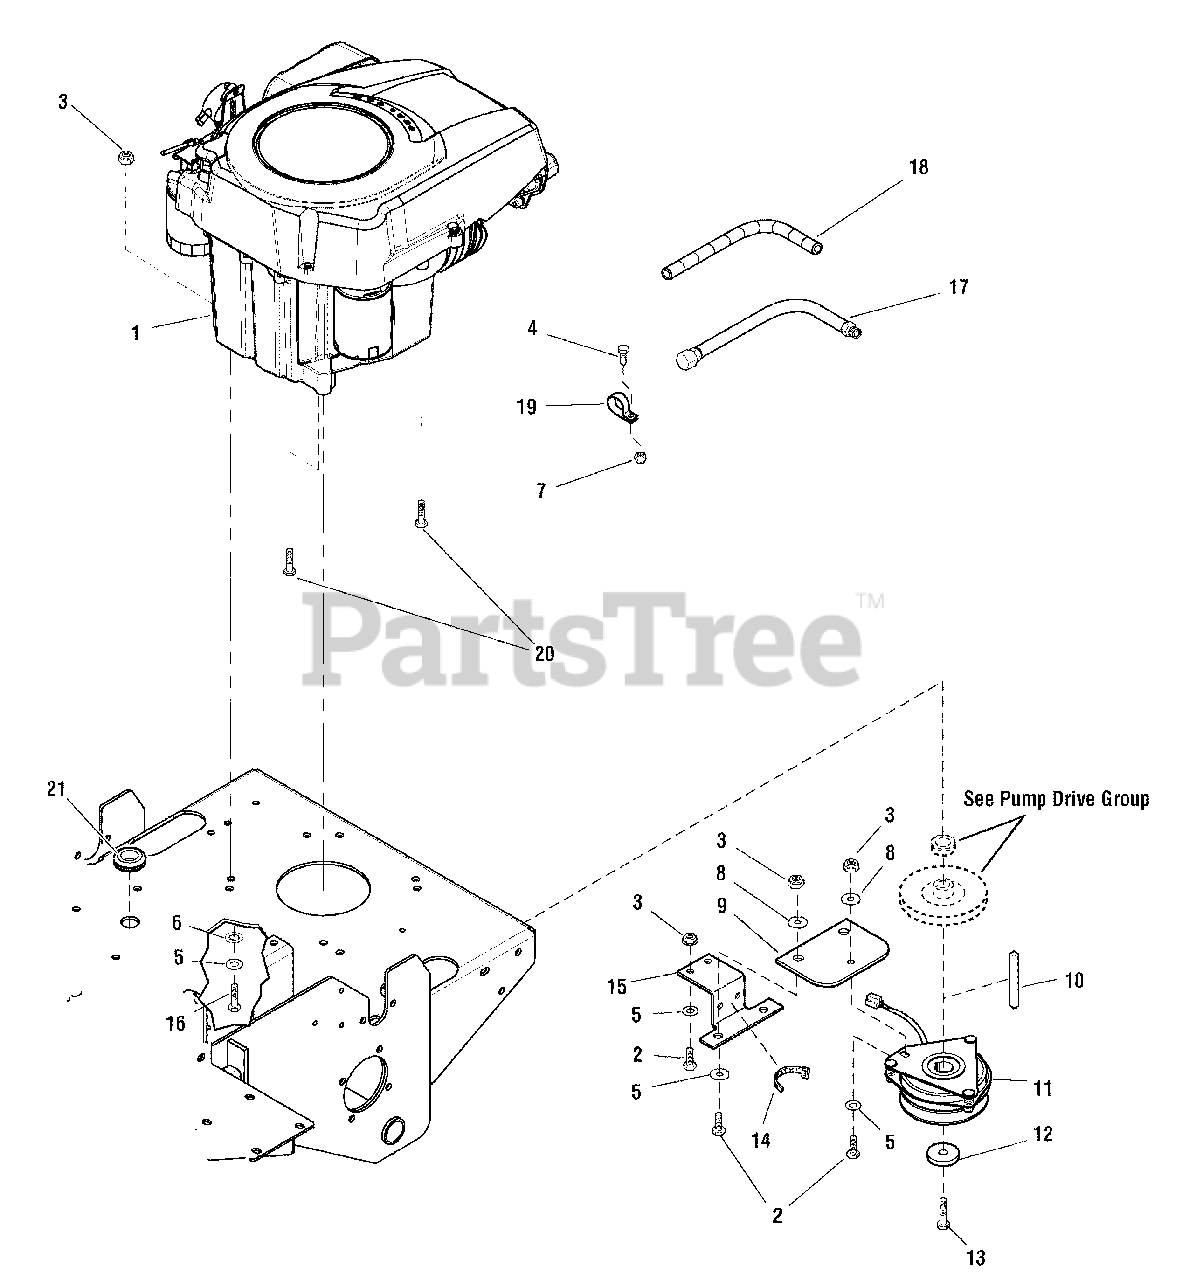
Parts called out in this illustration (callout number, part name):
1	* ENGINE, 18HP KOHLER Model SV540S, PS-552725
2	BOLT, 5/16-18 X 1
3	NUT, HEX NYLOCK FLANGE, 5/16-18
4	BOLT, 5/16-18 X 3/4 GD5
5	WASHER, 5/16" SAE
6	WASHER, 5/16 INT TOOTH LOCK
7	NUT, 1/4-20 HEX SERR. FLANGE
8	WASHER, CLUTCH ANCHOR, 5/16
9	CLUTCH ANCHOR PAD
10	KEY, 1/4 SQ. X 2-1/4
11	CLUTCH, ELECTRIC
12	SPACER, .45 X 1.62 X .37
13	BOLT, CRANKSHAFT, 7/16 X 3-1/4
14	TIE WRAP, 11" LONG
15	CLUTCH ANCHOR
16	BOLT, 5/16-18 X 1-3/4" GD5 YZ
17	HOSE, OIL DRAIN
18	WIRE LOOM, OIL DRAIN
19	CLAMP, VINYL INSULATED
20	BOLT, 3/8-16 X 1", SELF-TAPPING
21	GROMMET, 3/4"
